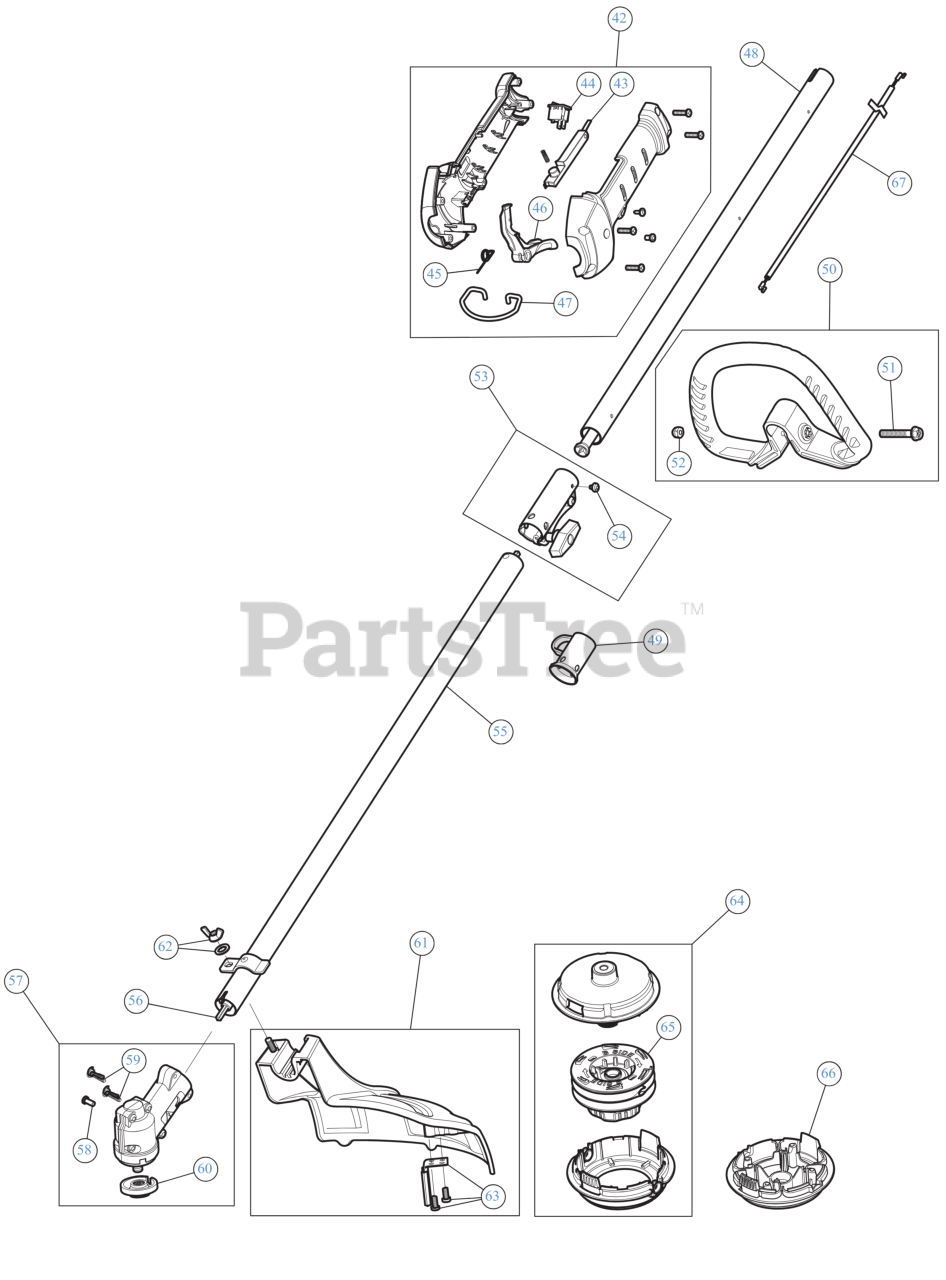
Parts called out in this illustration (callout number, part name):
42	THROTTLE GRIP ASM
43	LEVER LOCK OUT
44	SW, MOMENTARY ON/O
45	SPRING TRIG
46	THROTTLE TRIGGER
47	SHOULDER STRAP CLIP
48	UPPER BOOM ASSEMBLY
49	HANGER
50	HANDLE ASSEMBLY
51	BOLT 1/4-20X1 1/2
52	NUT 1/4-20 NYLOC
53	COUPLER ASSEMBLY
54	SCREW, 10-32X.250 TA
55	LOWER BOOM ASSEMBLY
56	LOWER DRIVE SHAFT
57	GEARBOX LCBC
58	SCREW, 8-32 x .312 P
59	SCREW #
60	CUTTING HEAD SPACER
61	GUARD/BLADE ASSEMBLY
62	BLADE GUARD MOUNTING HARDWARE
63	BLADE ASSEMBLY W/HDW
64	COMPLETE HEAD ASSEMBLY
65	BUMP KNOB
66	CAP ASSEMBLY W/PLUG
67	THROTTLE CABLE
